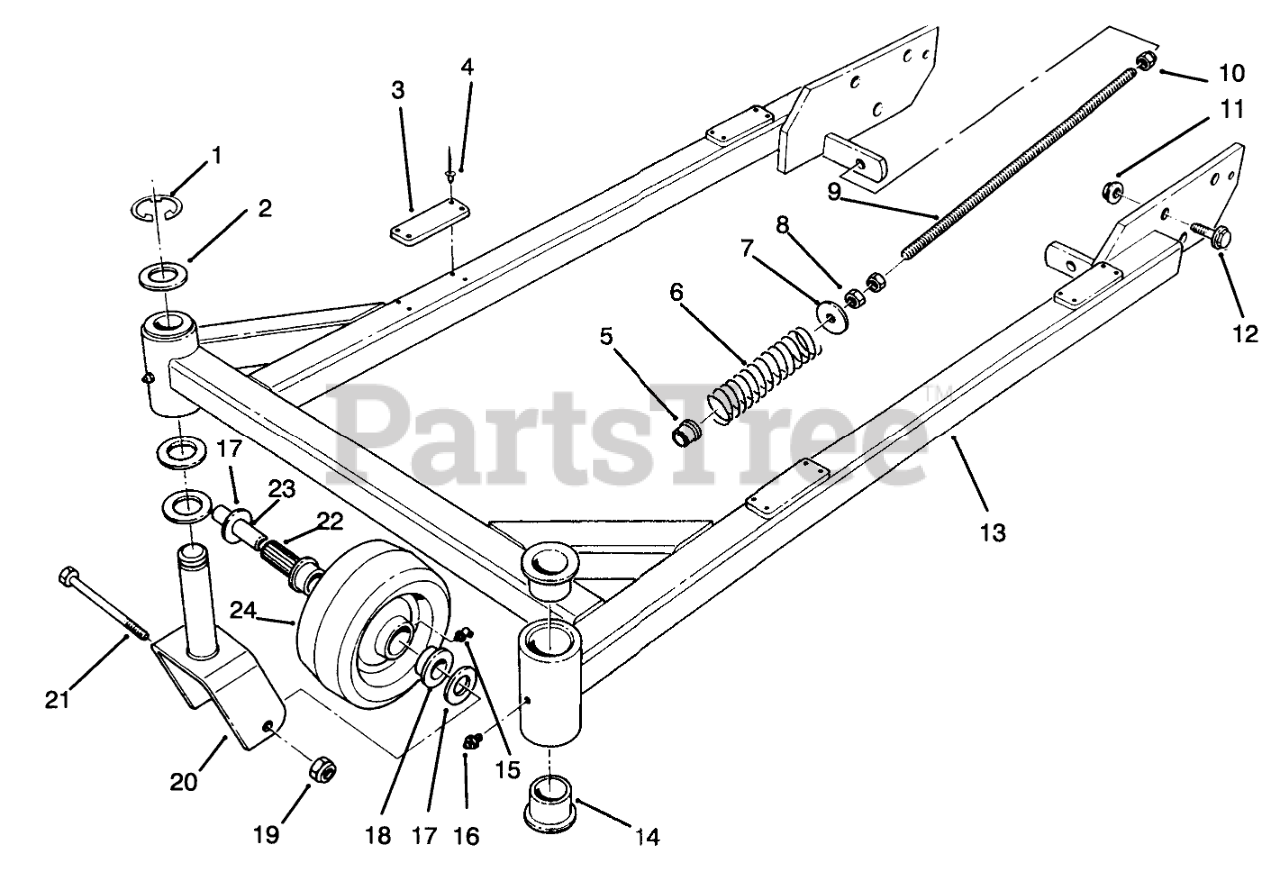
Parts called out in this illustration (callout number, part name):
1	RING-RETAINING
2	WASHER-THRUST
3	PAD-RUBBER
4	RIVET
5	BUSHING-FLANGE
6	SPRING
7	WASHER
8	NUT-JAM
9	SHAFT-ADJUSTING
10	NUT-LOCK, NI
11	NUT-HF
12	SCREW-HHF
13	Carrier Frame Assembly (Incl.Ref.#3,4,14 &16)
14	Bushing
15	FITTING-LUBE, 45 DEG
16	FITTING-GREASE
17	SPACER-WHEEL
18	BEARING-OUTSIDE
19	NUT-HEX
20	Fork-Castor
21	SCREW-HH
22	BEARING-ROLLER
23	SPANNER
24	Wheel Assembly-Castor (Incl. Ref. #15,18,& 22)
